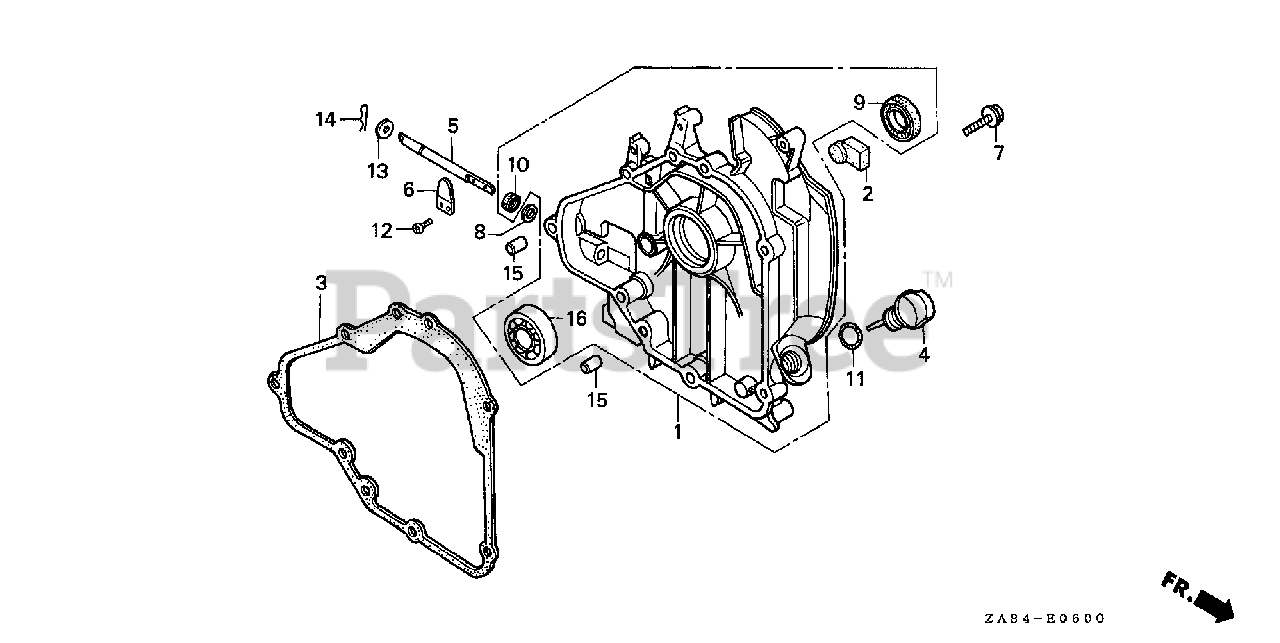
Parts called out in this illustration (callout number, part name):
1	COVER ASSY., CRANKCASE
2	RUBBER, BUMP STOP
3	GASKET, CASE COVER
4	CAP, OIL FILLER
5	SHAFT, GOVERNOR ARM
6	FORK, GOVERNOR
7	BOLT, FLANGE (6X25)
8	WASHER, THRUST
9	OIL SEAL (17X30X6) (NOK)
10	OIL SEAL (6X11X4)
11	O-RING (16MM)
12	SCREW, PAN (3X6)
13	WASHER, PLAIN (6MM)
14	PIN, LOCK (8MM)
15	PIN A, DOWEL (8X14)
16	BEARING, RADIAL BALL (6203)
